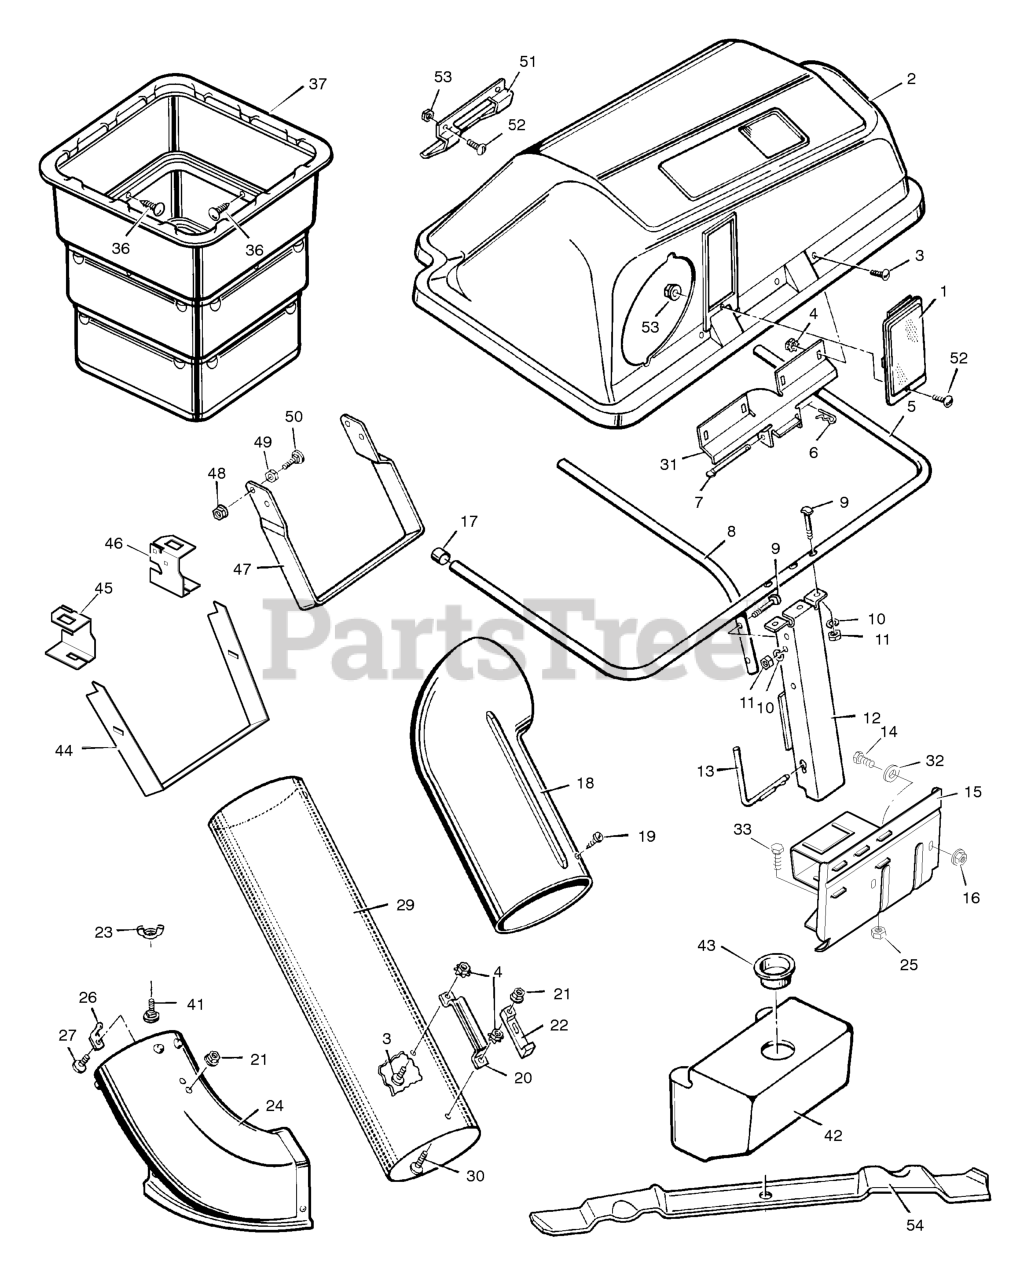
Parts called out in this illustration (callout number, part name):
4	Locknut
6	Pin, Hair
7	Pin, Hinge
8	Tube, Center
9	Bolt, Special
10	Lockwasher
11	Nut, Hex
12	Channel Assembly
13	Pin, Channel
14	CAPSCREW, Hex Head, 5/16-18 x 1
15	Mount Assembly, Bagger
16	Nut, Hex
17	Cap, End
20	HANDLE, Connect Tube
21	Locknut, Flange
22	Latch, Rubber
23	Wingnut
24	Tube, Extension
25	Hex Nut
26	Pin, Latch
27	Bolt, Carriage
29	Tube, Connector
31	Hinge, Cover
33	Bolt, Hex
36	Fastener, Plastic
37	Containers (Quantity 2)
41	Bolt, Carriage
42	Shell, Front Weight
43	Plug, Front Weight
44	Support, Weight (Type A)
45	Bracket, Right Hanger
46	Bracket, Left Hanger
47	Support, Weight (Type B)
48	Nut, Flange
49	Nut, Jam
50	Carriage, Bolt
51	Handle, Plastic
53	Nut, Hex
54	Blade, High Lift (97cm)
